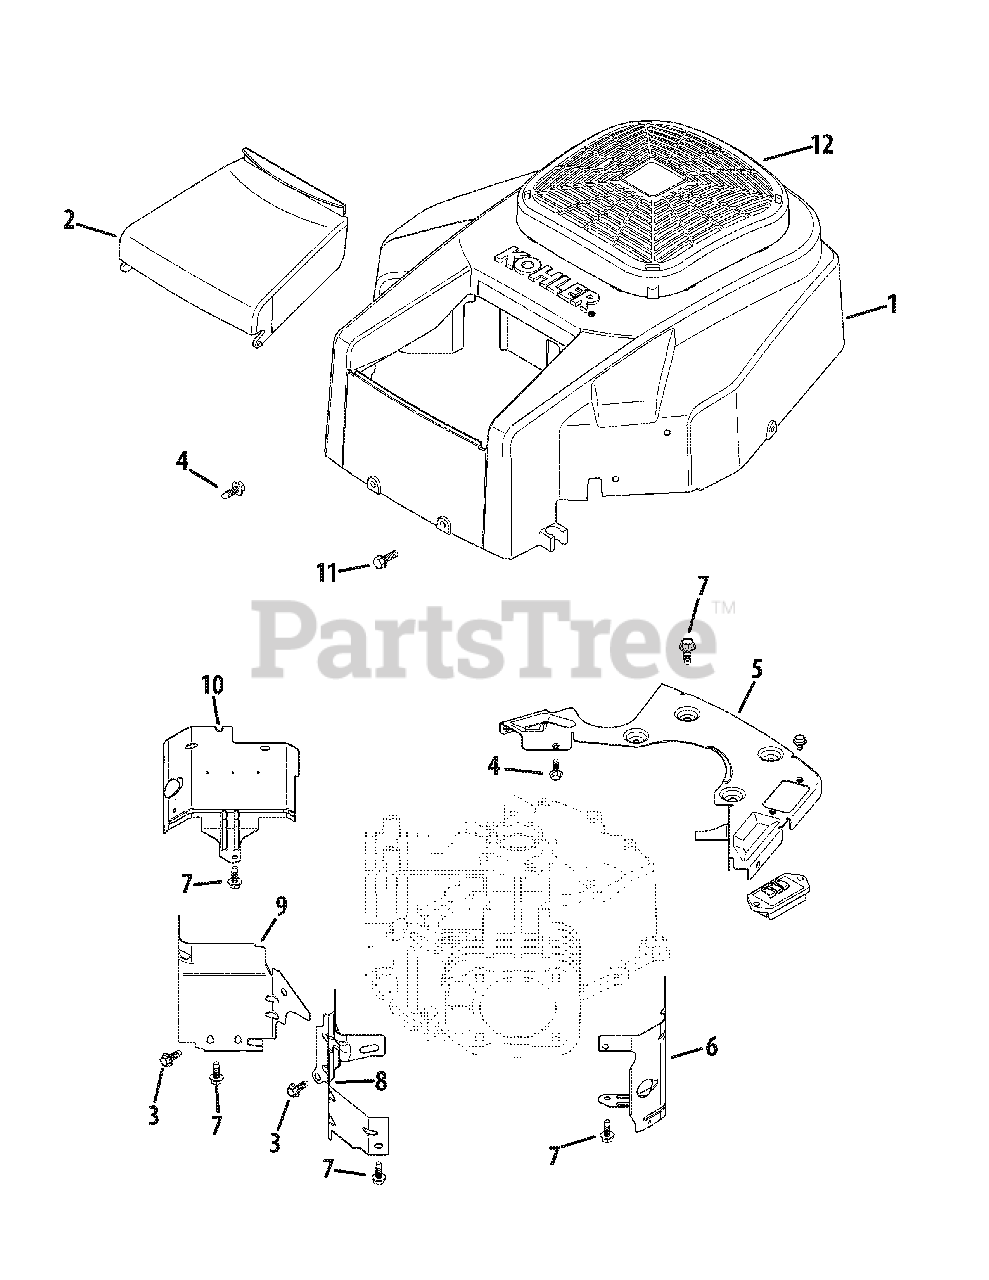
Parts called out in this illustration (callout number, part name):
1	Blower Housing Kit
2	Air Cleaner Cover
3	Flange Screw, M5 x .8 x 10
4	Flange Screw, M5 x .8 x 16
5	Backing Plate Kit
6	Cylinder Barrel Baffle, #2 Side
7	Flange Screw, M6 x 1.0 x 16
8	Valley Baffle, #2 Side
9	Valley Baffle, #1 Side
10	Cylinder Barrel Baffle, #1 Side
11	Tap Screw, M6 x 1.7 x 18
